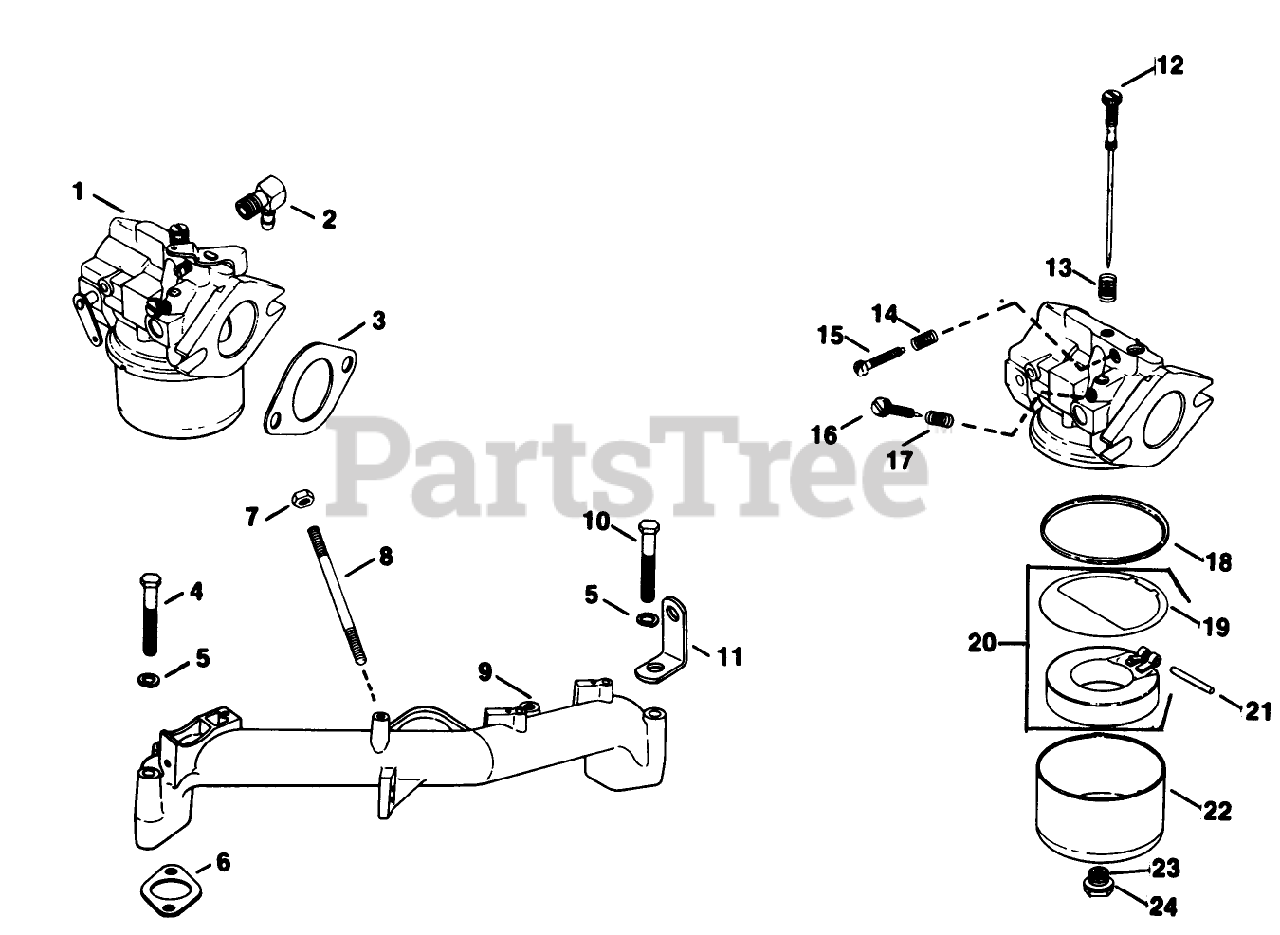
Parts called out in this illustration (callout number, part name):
1	Carburetor Assembly
2	Connector-90deg.
3	Gasket
4	Screw-H.C.
5	Washer
6	Gasket-Intake
7	Nut
8	Stud
9	Manifold-Intake
10	grew-H.C.
11	Strap-Lifting
12	Needle-Main Fuel Adj.
13	Spring-Main
14	Spring-Idle Speed
15	Screw
16	Needle-Idle Adj.
17	Spring-Idle
18	Gasket-Bowl
19	Gasket-Bowl Baffle
20	Kit-Float
21	Pin-Float Hinge
22	Bowl
23	Screw-Bowl Retainer
24	Gasket-Bowl Screw
